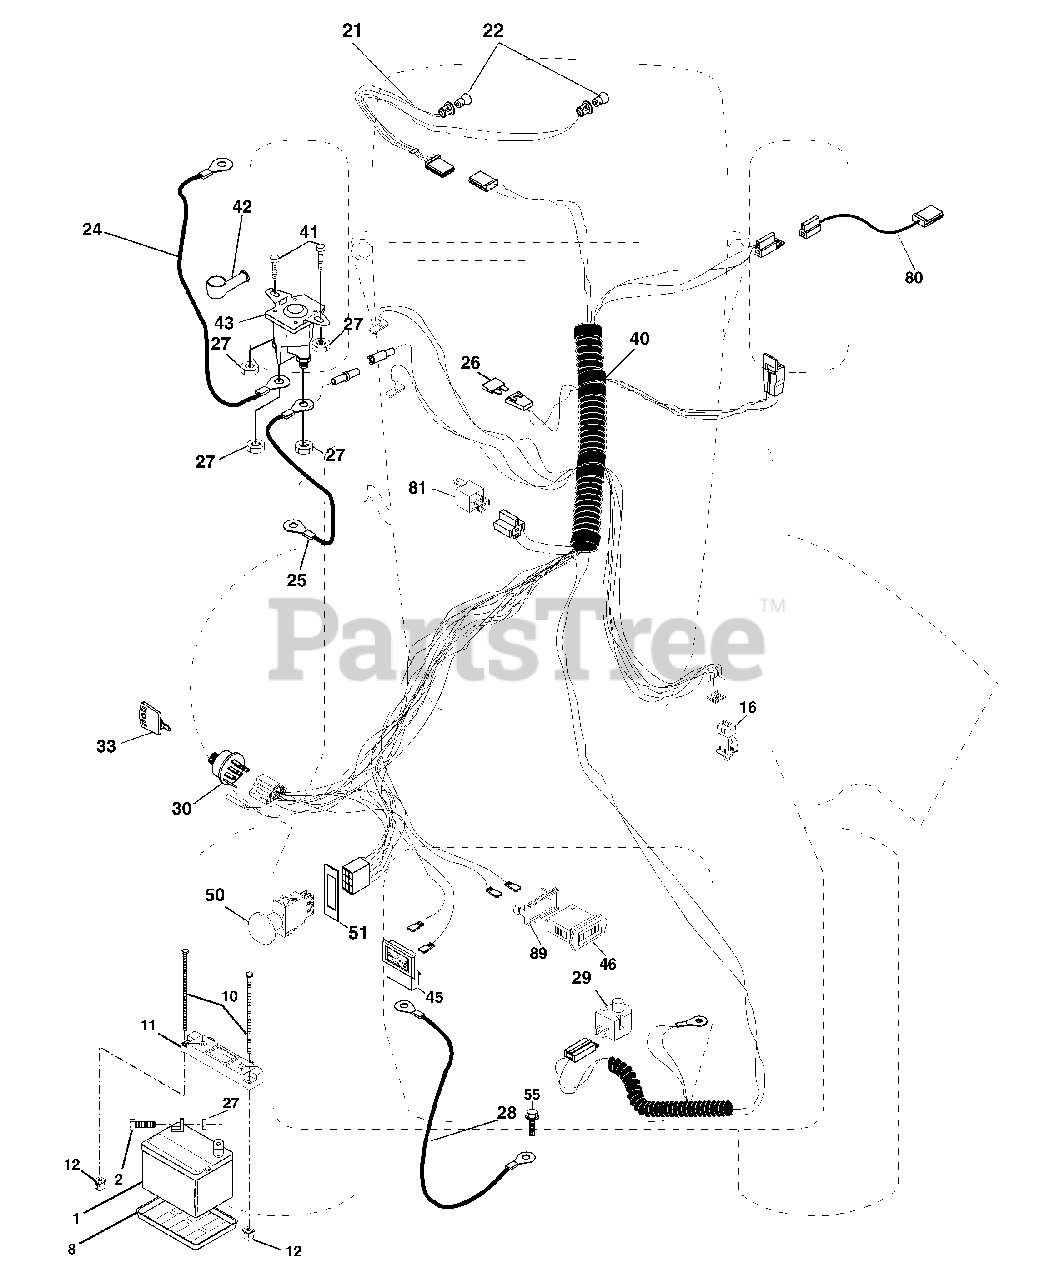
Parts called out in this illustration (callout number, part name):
1	Battery 12 Volt 35 AMP
2	Bolt Hex Hd 1/4-20unc X 3/4
8	Tray Battery
10	Bolt Brt Frt 1/4-20 x 75 Ainc
11	Hold down Battery Front Mount
12	Nut Push Nylon 1/4" Battery Frt
16	Switch Interlock Push-In
21	Harness Asm Light W/4152j
22	Bulb Light #1156
24	Cable Battery 6 Ga 11" red
25	Cable Battery 6 Ga 22" red w/16 wire
27	Nut Keps Hex 1/4-20 Unc
28	Cable Ground 6 Ga 21" black
29	Switch Plunger Nc Gray
30	Switch Ign
33	Key Ign Molded Generic
40	Harness Ign.
41	Bolt Blk Fin Hex 1/4 - 20 x 1/2
42	Cover Terminal Red
43	Solenoid
45	Ammeter Rectangular 15 Amp
46	Meter Hour
50	Switch PTO
51	Ring Retainer TTO
55	Screw Thdrol 5/16-18 x 1-1/2 Tyt
80	Harness Clutch Evx
81	Relay Asm.
89	Bracket Snap-In Hourmeter
